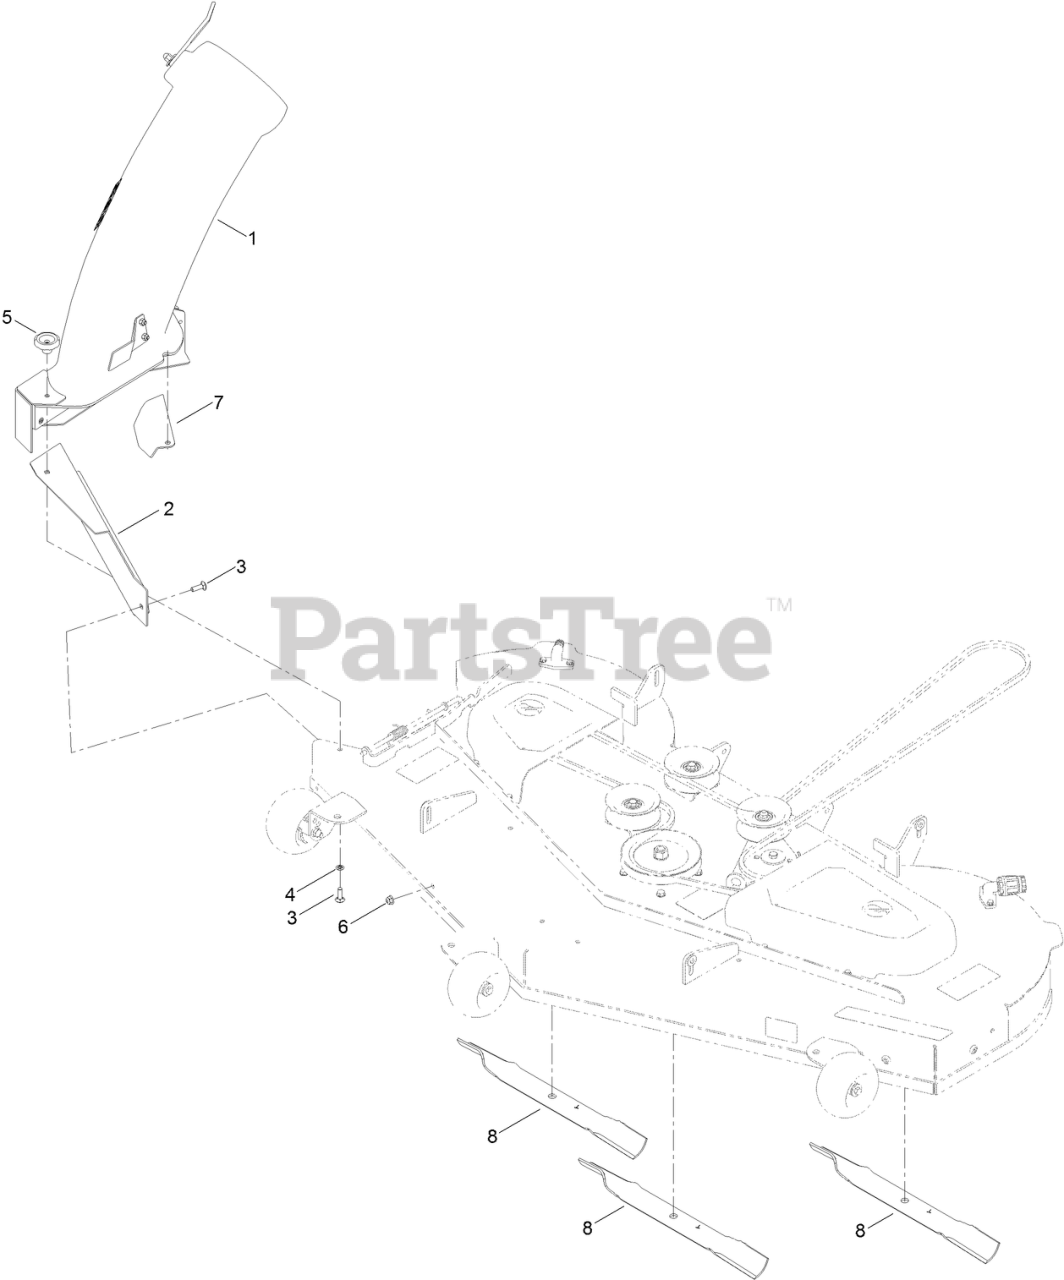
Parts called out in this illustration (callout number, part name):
1	60 INCH BAGGER BOOT ASM
2	BAFFLE-BAGGER, FRONT
3	SCREW-CARR
4	RING-RETAINING, BOLT
6	NUT-HF
7	BAFFLE-CUTOFF
8	BLADE-20.50 INCH
